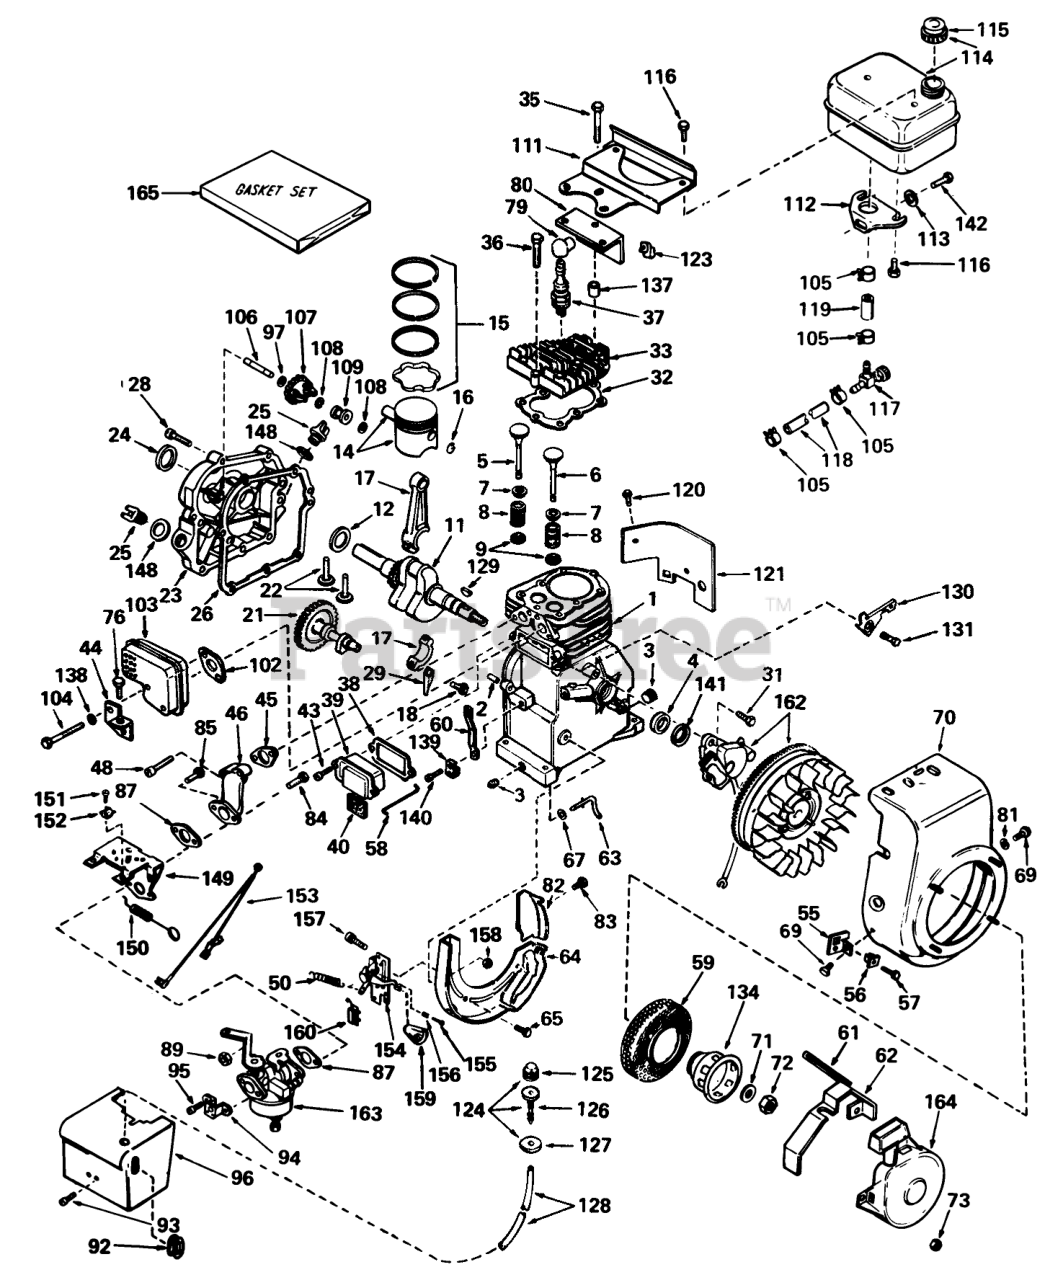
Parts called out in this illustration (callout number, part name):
1	Cylinder Assy. (Incl. #2, 3, & 4)
2	Pin-Dowel
3	Plug, Sq. Hd. Pipe, 1/4-18 (Oil Drain)
4	Seal-Oil
5	Valve, Intake (Std.) (Incl. #7, 8 & 9)
5	Valve, Intake (1/32 Oversize) (Incl. #7, 8 & 9)
6	Valve, Exhaust (Std.) (Incl. #7, 8 & 9)
6	Valve, Exhaust (1/32" Oversize) (Incl. #7, 8 & 9)
7	Cap-Upper Valve Spring
8	Spring-Valve
9	Cap-Valve, Spring
11	Crankshaft Assembly
12	Washer-Thrust
14	Piston, Pin & Ring Assy. (Incl. #15 & 16) (Std.)
14	Piston, Pin & Ring Assy. (Incl. #15 & 16) (.010 Oversize)
14	Piston, Pin & Ring Assy. (Incl. #15 & 16) (.020 Oversize)
15	Ring Set Piston (Std.)
15	Ring Set Piston (.010 Oversize)
15	Ring Set Piston (.020 Oversize)
16	Ring-Retaining, Piston Pin
17	Rod Assembly, Connecting (Incl. #18 & 29)
18	Bolt-Rod, Connecting
21	Camshaft
22	Lifter-Valve
23	Cover, Cylinder (Incl. #24, 25, 106 & 148)
24	Seal-Oil
25	Plug, Oil Filler (Incl. #148)
26	Gasket-Cylinder Cover
28	Screw
29	Dipper-Oil
32	63573 GIL 42 SNWTHW
33	Head Cylinder
35	Screw (5/16-18 X 2)
36	Screw (5/16-18x1-1/2)
37	Plug, Spark (J17LM or equiv.)
37	Plug, Spark (Champion RCJ-8)
38	Gasket Breather
39	Breather Assy. (Incl. #38 & 40)
40	Element-Breather
44	Bracket-Cover, Carburetor
45	Gasket, Intake
46	Pipe, Intake
48	Screw (1/4-20 x 1-19/32)
50	Spring-Extension
55	Bracket
56	Grommet
57	Screw
58	Link-Governor to Throttle
59	Screen-Starter
60	Lever, Governor
61	Seal, Snowguard
62	Guard-Starter
63	Rod-Governor
64	Baffle-Blower Housing
65	Screw (1/4-20x19/32)
67	Washer-Flat
69	Screw
70	Housing, Blower
71	Washer-Spring
72	Hex Nut
73	Nut and Lock Washer (1/4-28)
76	Screw (10-24 x 3/8)
79	Cover-Spark Plug
80	Baffle-Heat
82	Baffle-Extension
83	Screw-Hex Washer Hd.
84	Screw
85	Screw-Fil. Hd.
87	Gasket
89	Nut and Lock Washer (1/4-28)
92	Grommet, Carburetor cover
93	Screw (8-32 X 5/16)
94	Bracket-Choke
95	Screw (10-32 x 1/2)
96	Cover, Carburetor
97	Washer-Flat
102	Gasket-Intake
103	Muffler
104	Screw-Fil. Hd.
105	Clamp-Line, Fuel
106	Shaft-Governor
107	Gear Assy., Governor (Incl. #97)
108	Ring-Retaining
109	Spool-Governor
111	Plate-Fuel Tank
112	Bracket, Fuel Tank Lower
114	Tank Assembly, Fuel (Incl. #115 & 116)
115	Cap, Fuel
116	Screw (1/4-15x7/8)
117	Valve-Shut Off
118	Line-Fuel
119	Line-Fuel (8.62)
121	Extension-Blower
123	51004 GIL ROTARY TI
124	Primer, Assy. (Incl. #125, 126 & 127)
125	33164A GILO"HITCH A
126	Body Primer
127	Retainer, Primer Bulb
128	Line, Primer
129	Key, FIywheel
130	Bracket-Hold Down
131	Screw, Hex Hd. w/Conical
134	Cup, Starter
139	Clamp-Lever, Governor
140	Screw, Hex Washer Hd.
141	Gasket Stator
142	Screw Assembly
148	Gasket
149	Bracket, Speed Control
150	51011/13 TILL.O/P'7
151	Screw (10-32 x 3/8)
152	Conduit
153	Wire-Ground
154	Control Assembly, Speed (Incl. #155 thru 158 & 160)
155	Screw, Fil. Hd.
156	Spring-Compression
158	Nut-Lock
159	Knob-Control
160	Terminal
163	Carburetor (Incl.1 of #87)
164	Starter Assy., Rewind
165	Gasket
